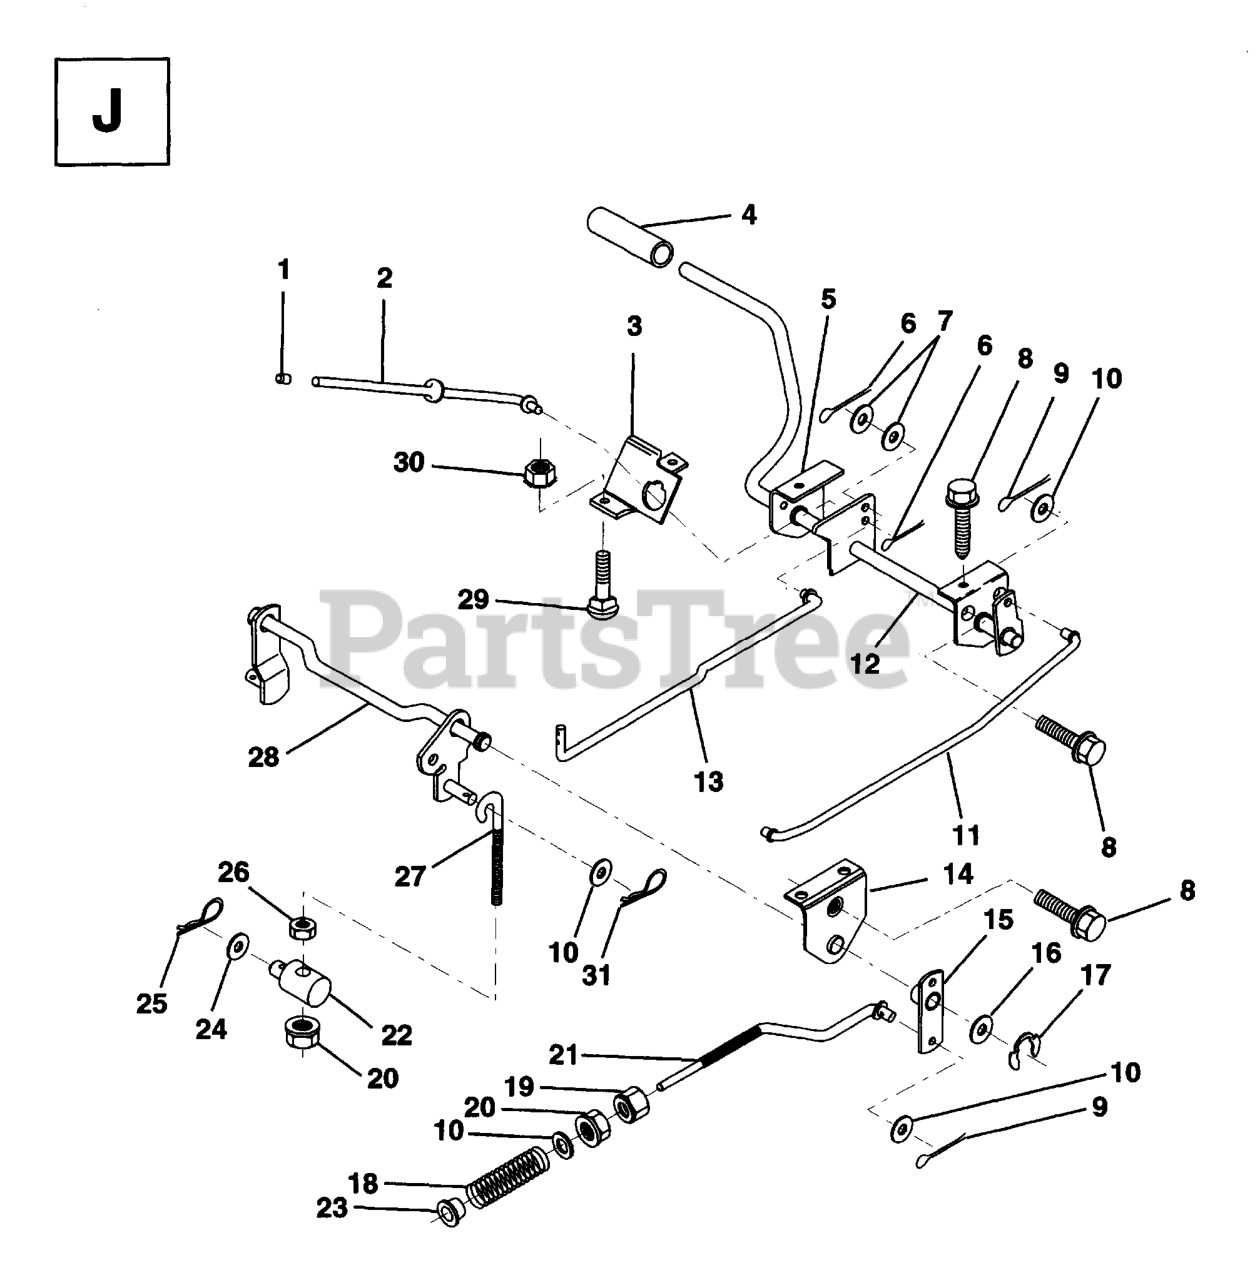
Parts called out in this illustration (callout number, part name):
1	PLUNGER CAP
2	ROD,PARK BRAKE
3	BRKT,PARK BRAKE
4	FOOT PEDAL COVER
5	BRKT,CLU PEDAL LH
6	COTTER PIN
8	Screw 5/16-18 x 1/2 Hex, Self Tapping 5/16-18 x 1/2
9	COTTER PIN
10	WASHER
11	ROD,FRT BRAKE
12	CLUTCH/BRAKE PEDAL ASSY
17	Ring, Klip Truarc #5304-75
18	SPRING ROD LT
19	NUT
22	TRUNNION, LEFT
23	BUSHING.DRAGLINK (2 2)
24	WASHER
25	SPRING TI
26	LOCKNUT
27	LINK.MOWER.REAR
28	REAR MOWER LIFT ASSY
